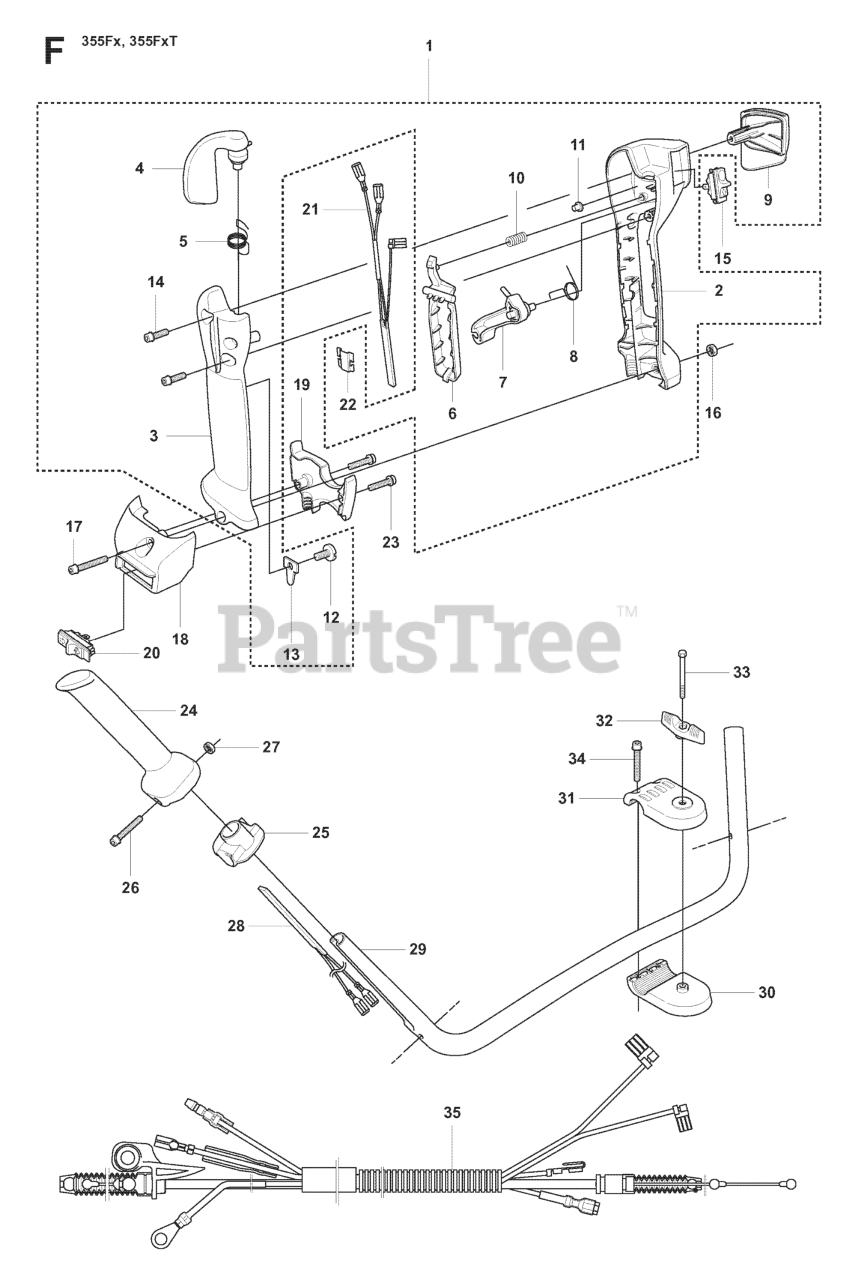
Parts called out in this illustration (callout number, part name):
1	THROTTLE HANDLE
2	HANDLE
3	HANDLE
4	THROTTLE TRIGGER
5	RP SPRING
6	THROTTLE LOCK
15	STOP BUTTON
16	NUT M6M M5
17	SCREW
18	HOLDER
19	HOLDER
20	SWITCH (G)
21	HEATING ELEMENT
23	SCREW
27	NUT M6M M5
28	HEATING ELEMENT
29	%HANDLE
30	HANDLE HOLDER LOWER
31	HANDLE HOLDER UPPER
33	%SCREW
35	WIRING
